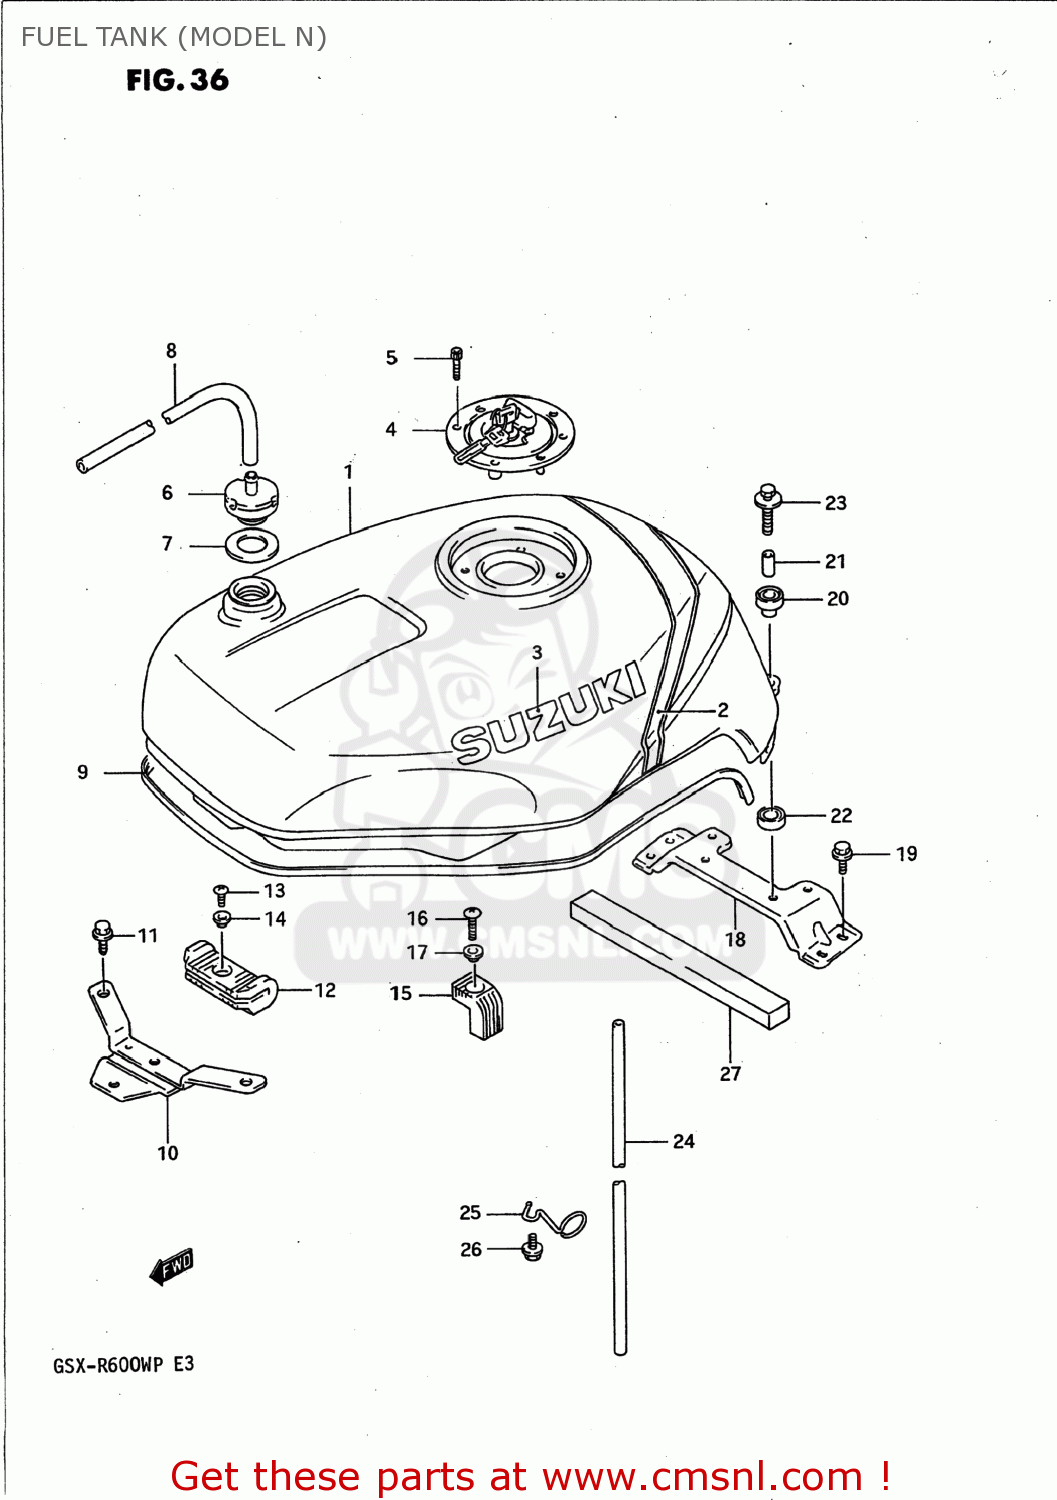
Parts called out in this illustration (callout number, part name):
1	TANK ASSEMBLY,FUEL
2	TAPE,FUEL TANK
3	EMBLEM,FUEL TANK
4	CAP SET,FUEL TANK
5	BOLT(5X20)
6	PLUG,FUEL TANK BREATHER
7	GASKET 27X40X2.5 (NAS)
8	HOSE(5X8.2X600)
9	MOLDING,FUEL TANK
10	BRACKET,FUEL TANK,FRONT
11	BOLT 6X16
12	CUSHION,FUEL TANK FR
13	SCREW 5X10
14	WASHER
15	CUSHION,FUEL TANK
16	SCREW
17	WASHER
18	BRACKET,FUEL TANK,REAR
19	BOLT 6X16
20	CUSHION
21	SPACER
22	CUSHION
23	BOLT ,6X35
24	HOSE (7X10.2X1000)
25	GUIDE,DRAIN HOSE
26	BOLT
27	CUSHION,AIR SEAL
